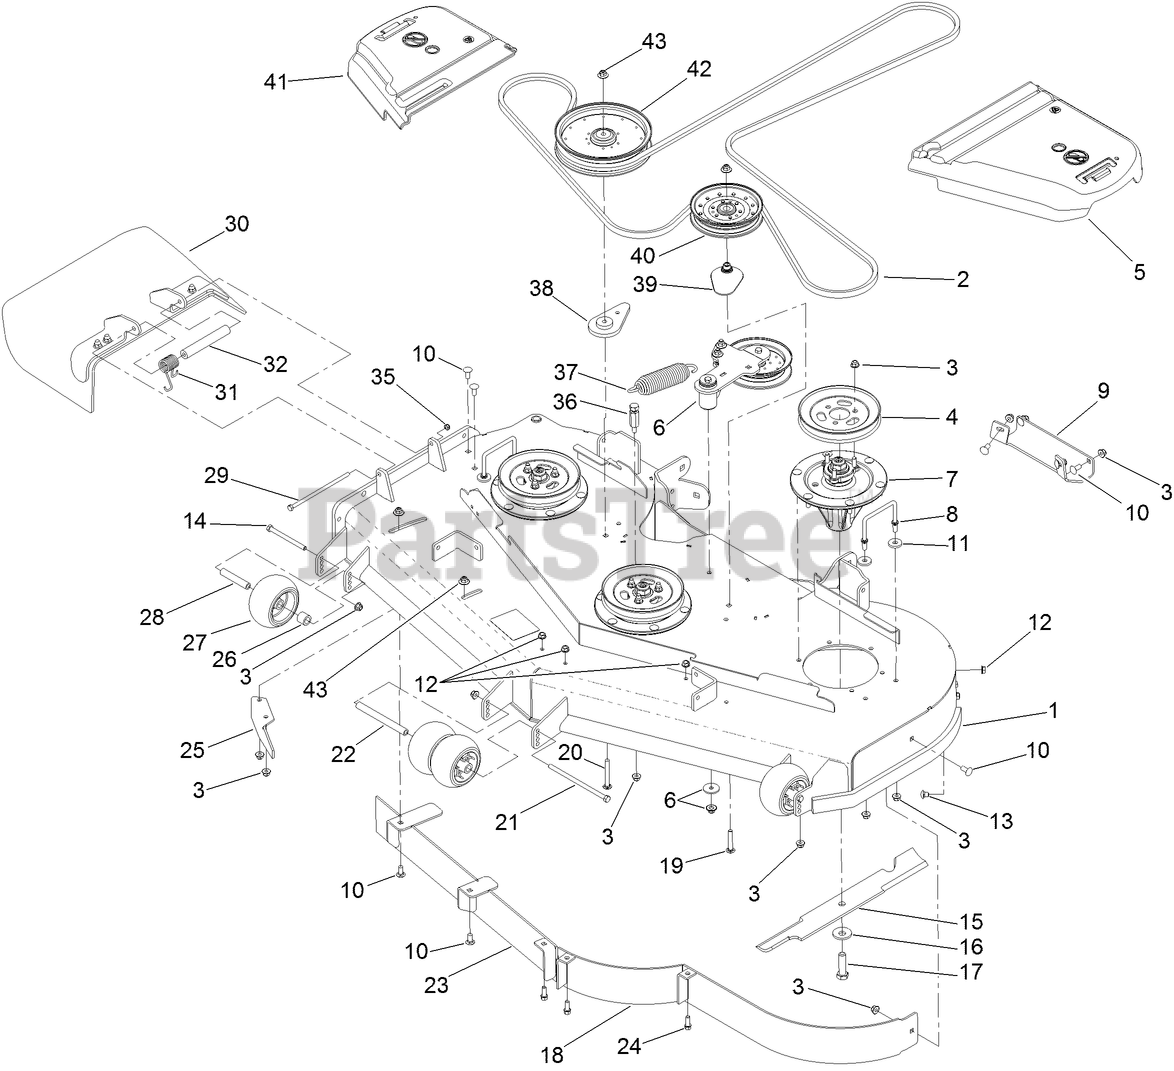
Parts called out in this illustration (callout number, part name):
1	DECK DECAL ASM
2	BELT-V
3	NUT-HF, NI
4	Pulley
5	COVER-BELT, LH
6	IDLER ARM ASM
7	SPINDLE ASM
8	WIREFORM-COVER
9	Plate-Skid
10	SCREW-CARR
11	WASHER
12	NUT-HHF, WHIZ
13	SCREW-CARR
14	SCREW-HH
15	BLADE-HI FLOW
16	Washer-Blade Bolt, Heavy
17	SCREW-BLADE
19	BOLT-CARR, SHORT NECK
20	SCREW-CARR
21	SCREW-HH
22	SPACER-WHEEL
24	SCREW-HWH
25	BAFFLE-DISCHARGE
26	TUBE-SPACER
27	ROLLER-SCALP, ANTI
28	TUBE-SPANNER
29	SCREW-HH
30	RUBBER DEFLECTOR ASM
31	SPRING-TORSION
32	SPACER
35	NUT-LOCK, NI
36	ANCHOR-SPRING, TALL
37	EXTENSION-SPRING
38	SPACER-IDLER
39	SPACER-PULLEY
40	PULLEY-IDLER, FLAT
41	COVER-BELT, RH
42	PULLEY-IDLER
43	NUT-FLANGE, NI
